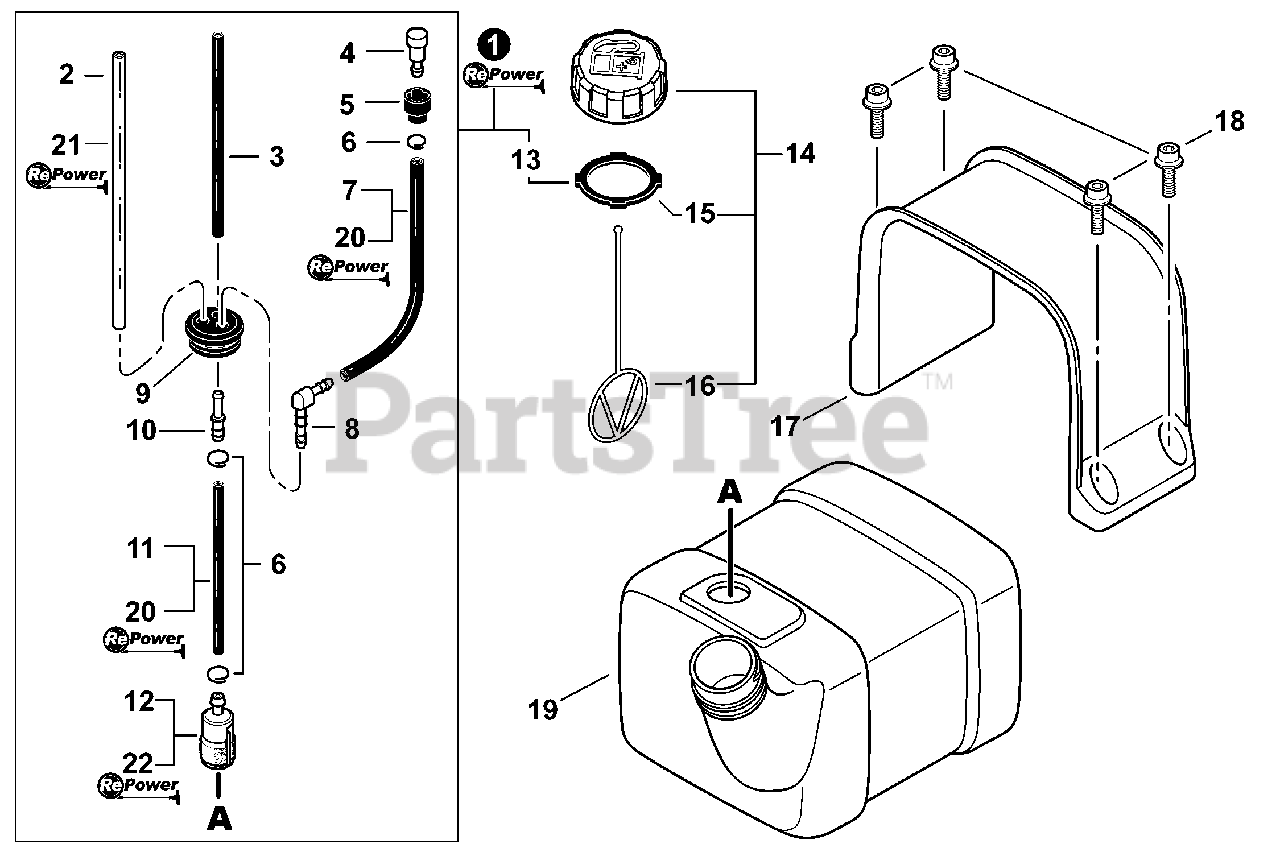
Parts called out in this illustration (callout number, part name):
1	FUEL SYSTEM KIT
2	PIPE, FUEL RETURN 3×6×145
3	PIPE, FUEL 3×5×110
4	VENT ASSY
5	HOLDER, VENT
6	CLIP Ø6.5 MM
7	PIPE, VENT 3×6×145 MM
8	CONNECTOR, PIPE
9	GROMMET, FUEL
10	CONNECTOR, PIPE Ø5ר3.5
11	PIPE, FUEL 3×6×120 BLACK
12	FILTER, FUEL
13	GASKET, FUEL CAP
14	CAP ASSY, FUEL
15	GASKET, FUEL CAP
16	CONNECTOR, CAP L= 100 MM
17	BRACKET, FUEL TANK
18	BOLT 5×16
19	TANK, FUEL
20	BULK PIPE - 3×6 MM BLACK (4 PIECES×2 M)
21	BULK PIPE - 3×6 MM CLEAR (4 PIECES×2 M)
22	TUNE-UP KIT - REPOWER
